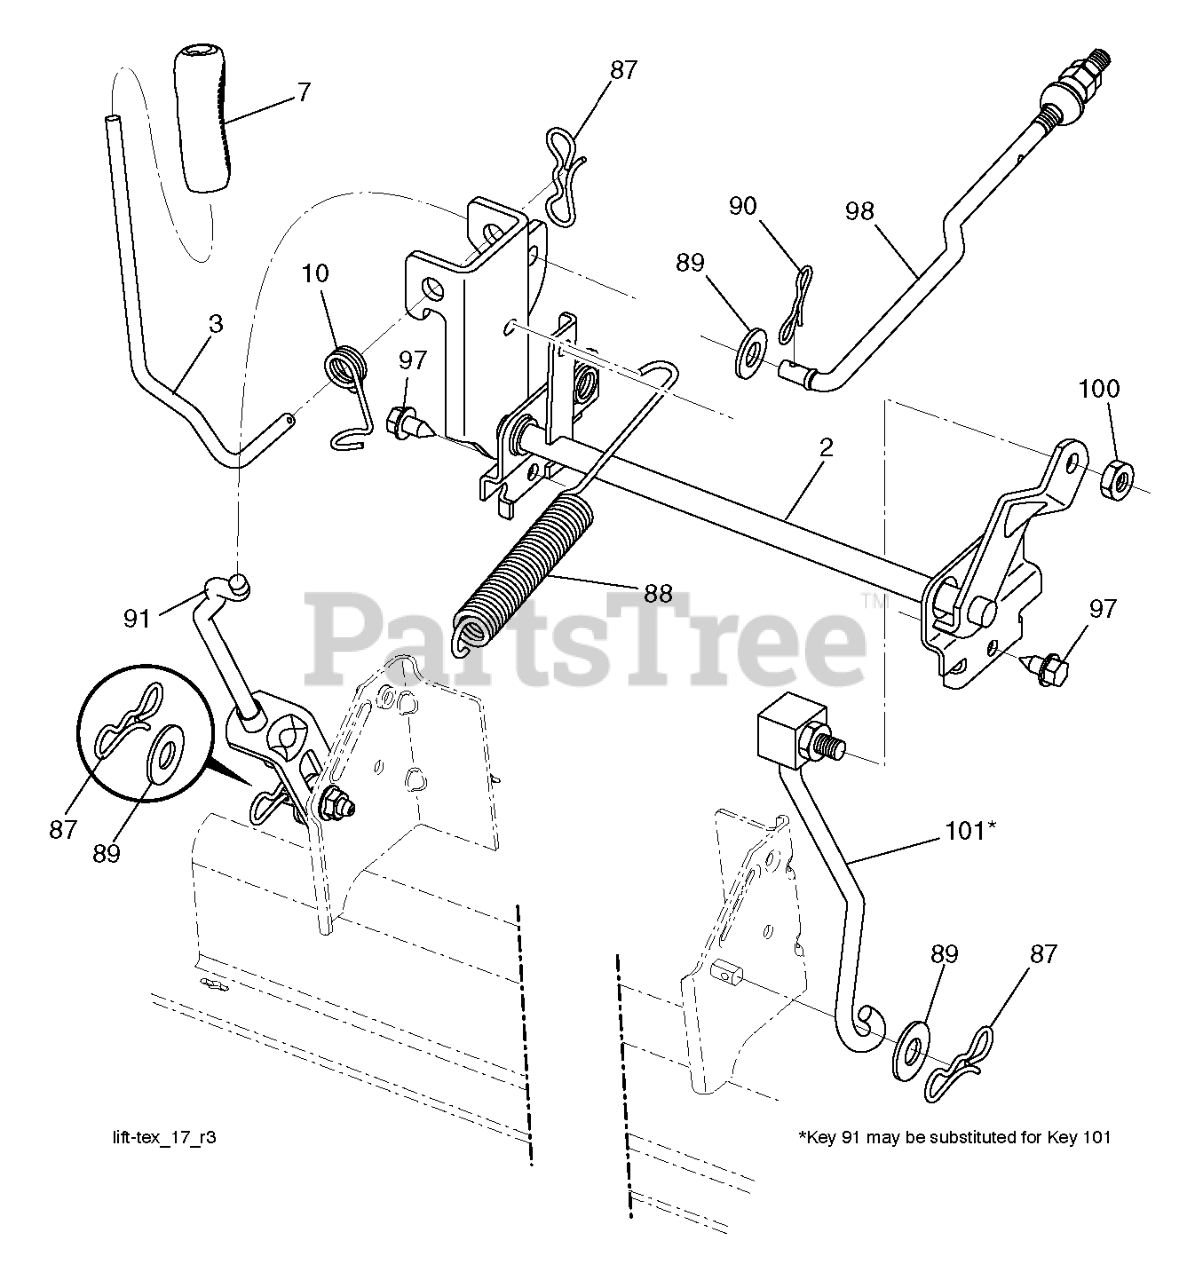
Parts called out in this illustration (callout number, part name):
2	SHAFT LIFT DECK WELD
3	LEVER.LIFT.HANDLE.LT
7	GRIP.HANDLE.LIFT.PVC.BLACK
10	SPRING.TORSION.LIFT.HANDLE
87	PIN.COTTER.7/16.BOW TI.
88	SPRING SPRING LIFT ASSIST 97
89	WASHER.CLEAR.ZINC
90	PIN.COTTER.5/16.BOW TI
91	LINK.ASM.LIFT.REAR
97	SCREW LT
98	LINK.ASM.SUSP.FRONT.MW
100	LOCKNUT
101	LINK.ASM.LIFT.FIXE.38/42/46"
